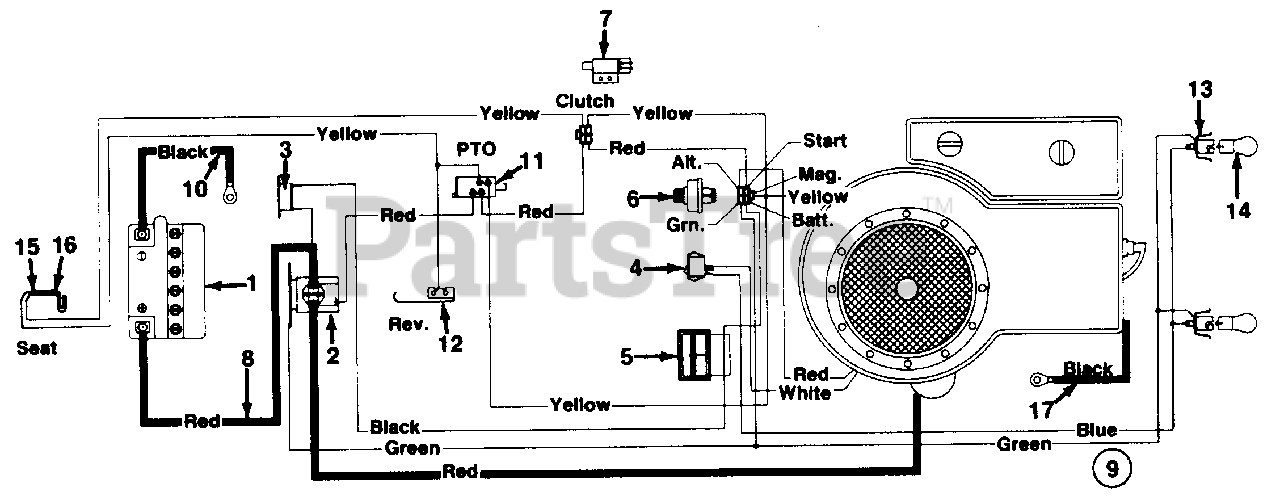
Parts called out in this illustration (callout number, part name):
1	Battery
2	Solenoid
3	Circuit Breaker
4	Light Switch
5	Ammeter
6	Ignition Switch
7	Safety Switch (Clutch)
8	Electric Wire 8" Lg.
9	Wire Harness
10	Ground Wire 11.5" Lg.
11	Safety Switch (Deck)
12	Safety Switch (Reverse)
13	Socket
14	Bulb
15	Safety-Switch (Seat)
16	Safety Switch (Seat)
17	Ground Wire 7.5" Lg.
